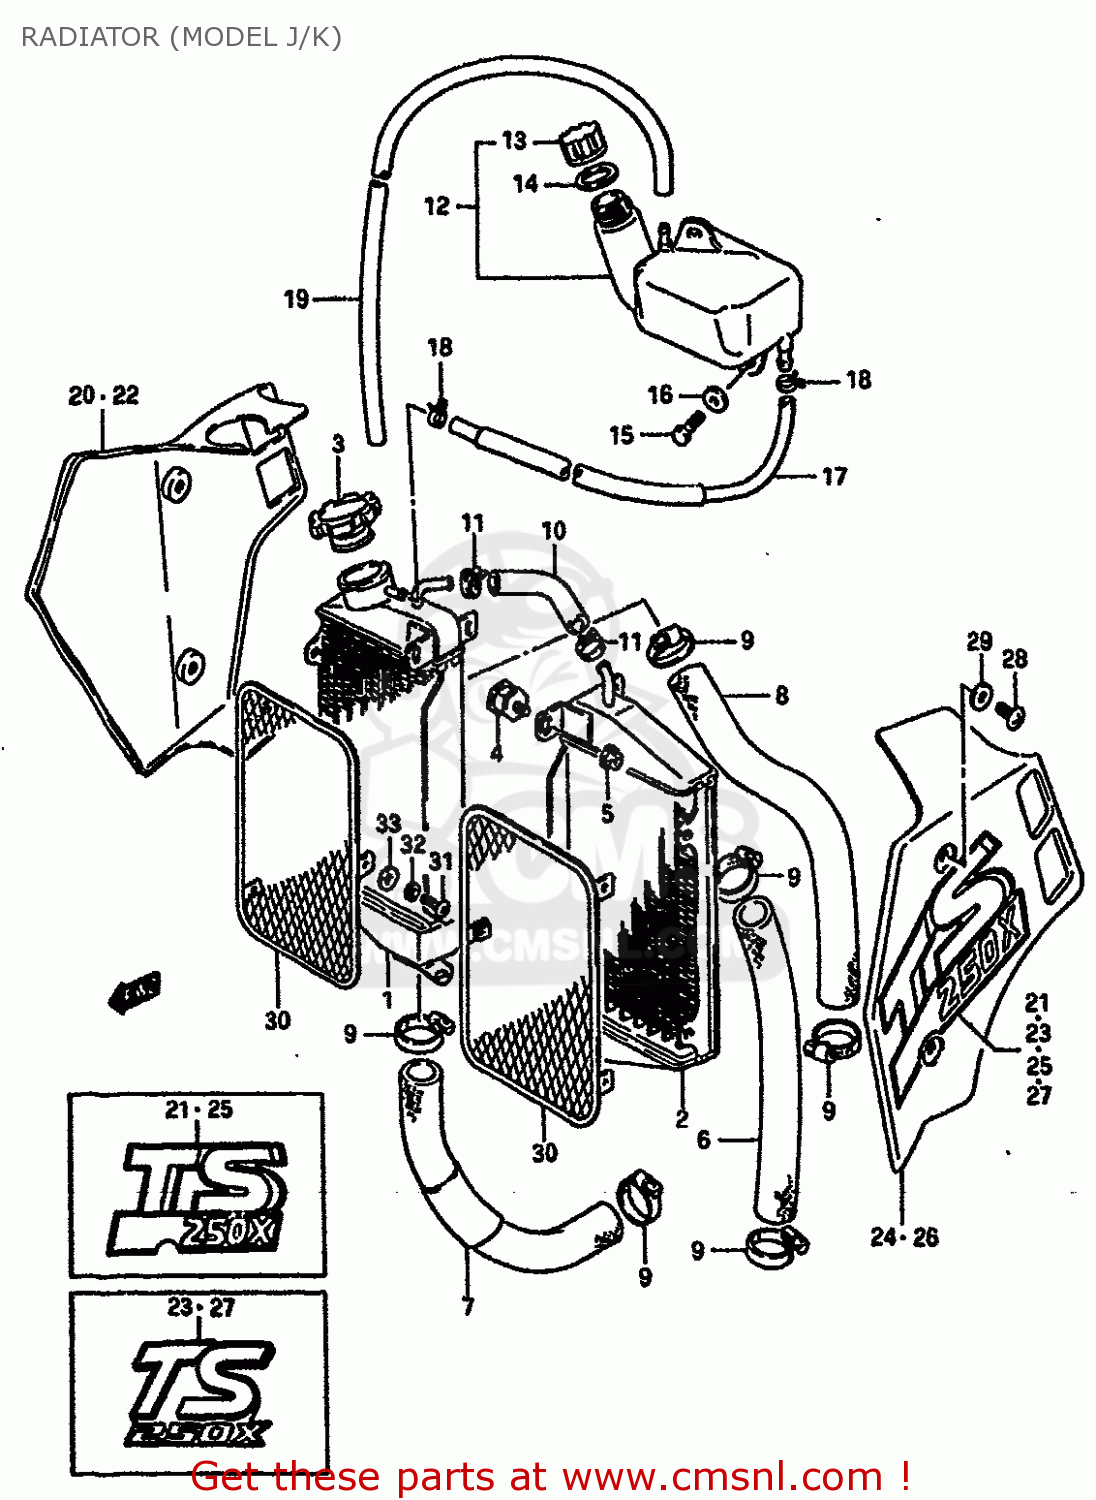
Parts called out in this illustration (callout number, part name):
1	RADIATOR,WATER RH
2	RADIATOR,WATER LH
3	CAP
4	BOLT,RADIATOR CUSHION
5	NUT 6MM
6	HOSE,RADIATOR INLET
7	HOSE,RADIATOR OUTLET
8	HOSE,RADIATOR JOINT
9	CLAMP
10	HOSE,RADIATOR BY-PASS
11	CLIP
12	TANK ASSY,RESERVER
13	CAP,RESERVOIR TANK
14	GASKET,RESERVOIR TANK CAP (NAS)
15	SCREW
16	WASHER
17	HOSE,RESERVER TANK INLET
18	CLIP
19	HOSE
20	COVER,RADIATOR RH (WHITE)
21	TAPE,RADIATOR COVER RH
22	COVER,RADIATOR RH (BLACK)
23	TAPE,RADIATOR COVER
24	COVER,RADIATOR LH (WHITE)
25	TAPE,RADIATOR COVER LH
26	COVER,RADIATOR LH (BLACK)
27	TAPE,RADIATOR COVER
28	SCREW
29	WASHER
30	BUMPER,RADIATOR
31	SCREW
32	WASHER,LOCK
33	WASHER
34	CLAMP(L:220)
